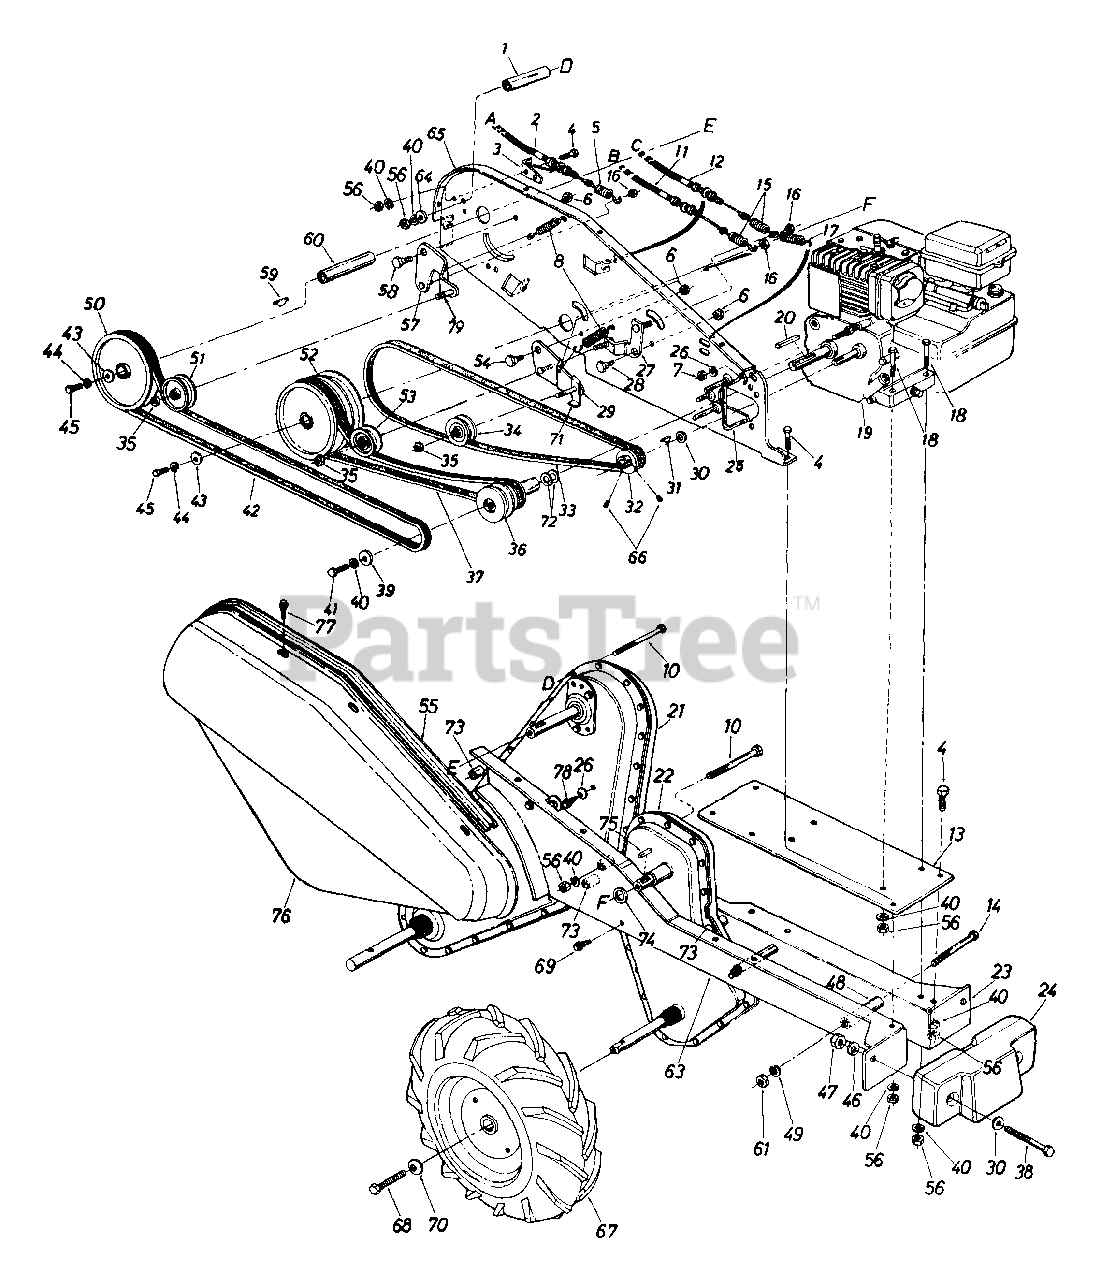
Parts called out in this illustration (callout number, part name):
1	Spacer .375" I.D. x .5" O.D. x 2" Lg.
2	Clutch Control Cable (Tines)
3	Clutch Cable Bracket
4	Hex Bolt 5/16-18 x .75" Lg.
5	Extension Spring .50" O.D. x 2.5" Lg.
6	Hex Cent. L-Nut 3/8-16 Thd.
7	Hex Nut 1/4-20 Thd.
8	Extension Spring .50" O.D. x 1.55" Lg.
10	Hex Bolt 5/16-18 x 3" Lg.
11	Clutch Control Cable 42" Lg. (Forward)
12	Clutch Control Cable 42" Lg. (Reverse)
15	Springs
16	Hex Cent. L-Nut 1/4-20 Thd.
17	Extension Spring .41" O.D. x 2.05" Lg.
18	Hex Bolt 5/16-18 x 1.5" Lg.
19	Engine
20	Sq. Key 3/16 x 1.00" Lg.
21	Chain Case Comp.- Tines
22	Chain Case Comp.- Wheels
25	Belt Keeper
26	Bell-Wash..265" I.D. x .75" O.D.
29	Idler Brkt. Ass'y.(Wheel Forward)
30	Fl-Wash..51" I.D. x 1.0"
31	#5 Hi-Pro-Key 1/8" x 5/8" Dia.
32	1/2" V-Pulley 2.25" O.D. x .503" I.D.
33	"V"-Belt
34	"V"-Belt Idler 2.62" O.D.
35	Hex ins. L-Nut 3/8-24 Thd.
36	1/2" "V"-Pulley Ass'y.
37	"Y"-Belt
38	Hex Bolt 1/2-13 x 4" Lg.
39	Fl-Wash..344" I.D. x 1.125"
40	L-Wash. 5/16" I.D."
41	Hex Bolt 5/16-24 x 1.00" Lg.
42	"V"-Belt
43	Fl-Wash. 1/4" I.D. x .93" O.D.
44	L-Wash 1/4" I.D.
45	Hex Bolt 1/4-28 x 75" Lg.
46	L-Wash. 1/2" I D.
47	Hex Nut 1/2-13 Thd."
48	Spacer .38" I.D x .62" O D. x 2.18" Lg.
49	L-Wash 3/8" I.D."
50	Fl-Pulley w/Flanges 6" O.D.
51	Fl-idler w/Flanges 3.75" O.D.
52	Double Fl-Pulley 5/8" I.D.
53	Fl-Idler w/Flanges 2.12" O.D
54	Shld. Bolt .500" Dia. x 170" Lg.
55	Flange Extension
56	Hex Nut 5/16-18 Thd.
59	#61 Hi-Pro-Key 3/16" x 5/8" Dia.
60	Spacer .647" I.D. x 2.75" Lg.
61	Hex Nut 3/8-24 Thd.
65	Side Plate Ass'y.
66	Set Scr. 1/4-28 x .25" Lg.
67	R.H. Wheel Ass'y. Comp. 13 x 5
68	Hex Bolt 5/16-24 x .62" Lg.
69	Hex Self-Tap Scr. 5/16-24 x .5" Lg.
70	Bell-Wash. 5/16" I.D.
71	Belt Keeper Brkt.
72	Fl-Wash..76" I.D. x 1.5"
73	Spacer .326" I.D. x.47" O.D. x .96" Lg.
74	Fl-Wash..635" I.D. x 1" O.D.
75	Sq. Key 3/16 x .75" Lg.
78	Hex Wash. S-Tap Scr. 1/4-20 x .38" Lg.
79	Hex Bolt 3/8-24 x 1.25" Lg."
